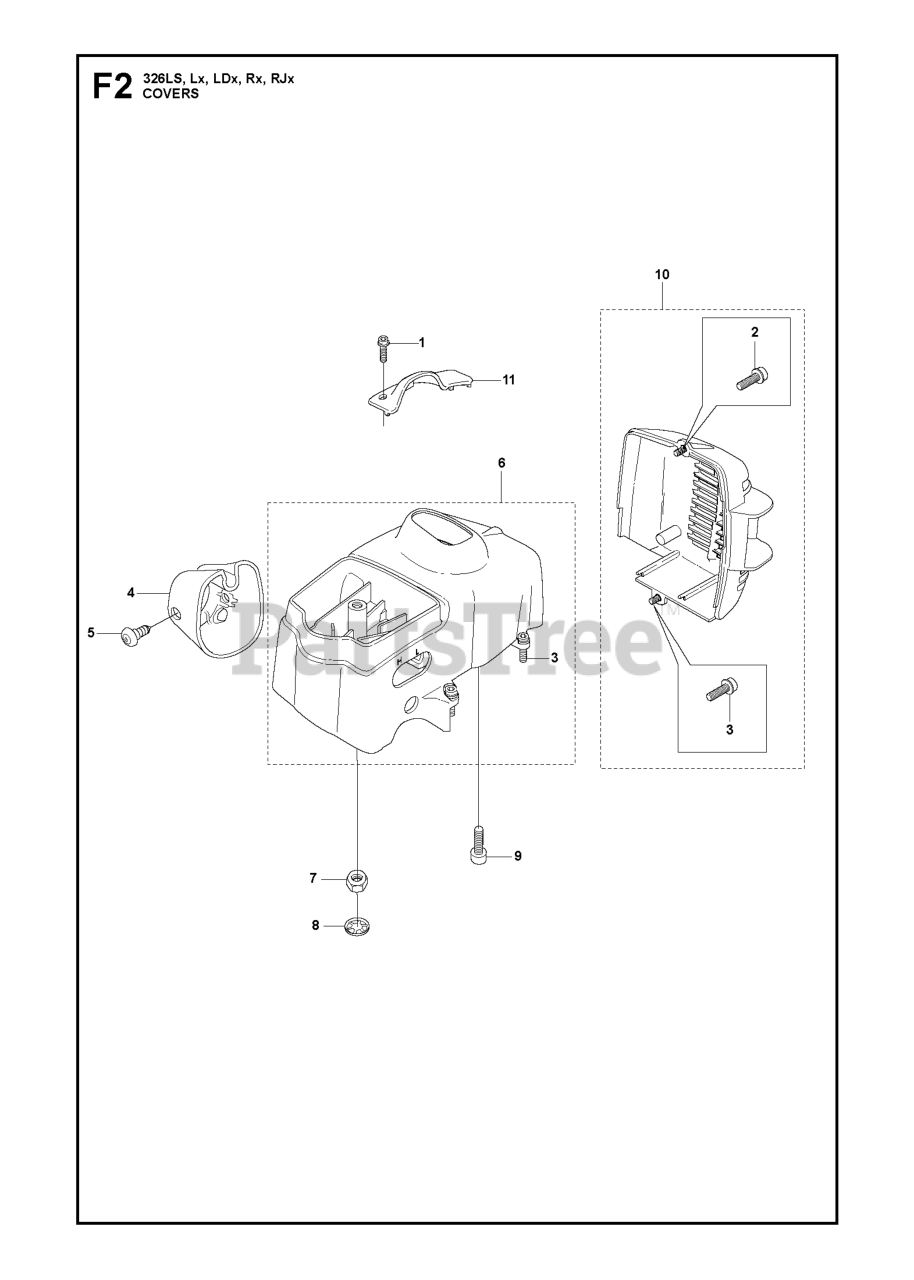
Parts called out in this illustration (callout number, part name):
2	SCREW IHSCFTO
3	SCREW IHSCFMO
4	COVER
5	SCREW MT5X11
6	CYLINDER COVER
9	SCREW
10	GUARD MUFFLER
